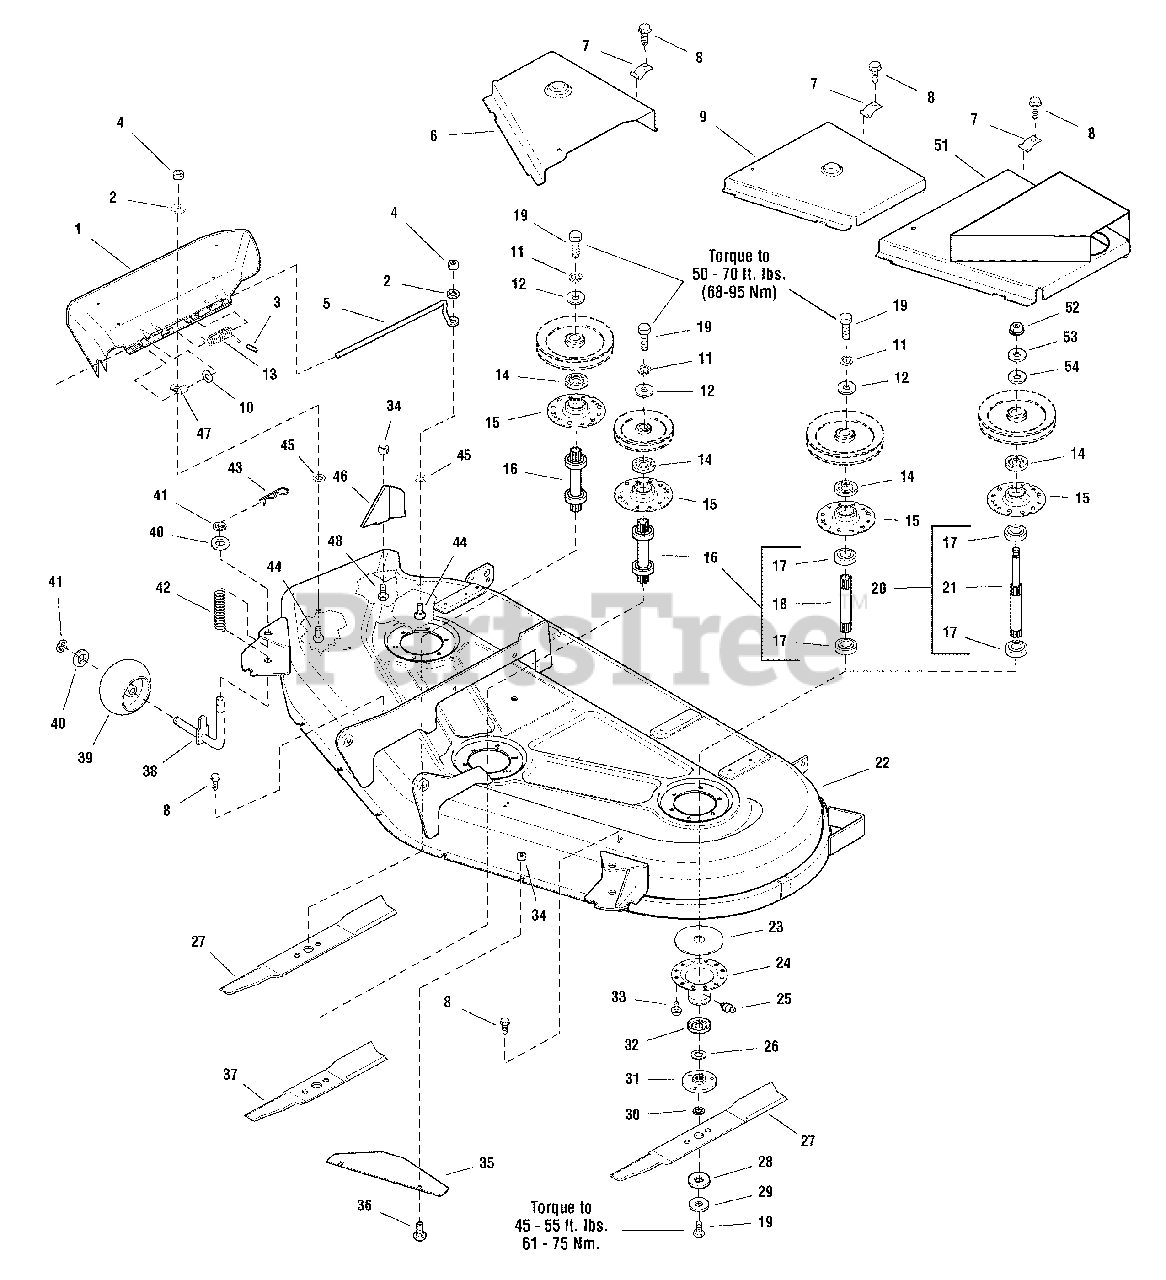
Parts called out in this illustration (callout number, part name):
1	DEFLECTOR, Plastic
2	WASHER, Plain, 1/4
3	CAP, Spring End
4	NUT, Hex, Lock ESNA, 1/4-20, Black
5	ROD, Deflector, Front
6	COVER, Arbor, RH (Orange)
6	COVER, Arbor, RH (Red)
7	CLIP, Spring
8	SCREW Hex Head, Taptite,1/4-20 x 3/8
9	COVER, Arbor, LH Landlord (Orange)
9	COVER, Arbor, LH Legacy XL (Orange)
9	COVER, Arbor, LH (Red)
10	WASHER, Plain, 5/16
11	WASHER, Lock, 7/16
12	WASHER, 7/16
13	SPRING, Torsion
14	SHIELD, Bearing Upper, Arbor
15	HOUSING, Arbor, Top
16	ARBOR SHAFT & BEARING ASSEMBLY (Includes Ref. Nos. 17 & 18)
17	BEARING, Ball, 3/4 x 1-3/4 x 5/8
18	ARBOR SHAFT
19	CAPSCREW, Hex Head, 7/16-14 x 1-1/4, G8
20	ARBOR SHAFT & BEARING ASSEMBLY
21	ARBOR SHAFT
22	HOUSING ASSEMBLY, 54" Legacy 4WD (Orange)
22	HOUSING ASSEMBLY, 54" Legacy XL (Orange)
22	HOUSING ASSEMBLY, 54" 2700 4WD (Red)
22	HOUSING ASSEMBLY, 54" Landlord (Black)
23	GASKET, Foam
24	ASSEMBLY, Housing, Bottom (Includes Ref. No. 25)
25	FITTING, Lube
26	WASHER, Shim
27	BLADE, Mower, 20-1/2
28	WASHER, Spline
29	WASHER, Spring
30	RING, Self Locking
31	ADAPTER, Blade
32	SHIELD, Grass
33	CAPSCREW, Hex Head, Taptite, 5/16-18x 3/4, Black
34	NUT, Hex, KEPS, 5/16-18, Black
35	BAFFLE, Front, Anti-Blowout
36	CARRIAGE BOLT, 5/16-18 x 3/4
37	BLADE, Mower, 16
38	SPINDLE, Assembly
39	WHEEL, Gauge
40	WASHER, Plain 1/2
43	PIN, Hairpin
44	CARRIAGE BOLT, 1/4-20 x 1, Black
45	NUT, Push
46	BAFFLE, Discharge
47	CLAMP, Wire
48	CAPSCREW, Hex Head, 5/16-18 x 5/8, Black
51	ASSEMBLY, Cover, Arbor (Black)
51	ASSEMBLY, Cover, Arbor (Orange)
52	NUT, Hex Flange 9/16-18
53	WASHER, Belleville .05 Thick
54	WASHER, 1/2
